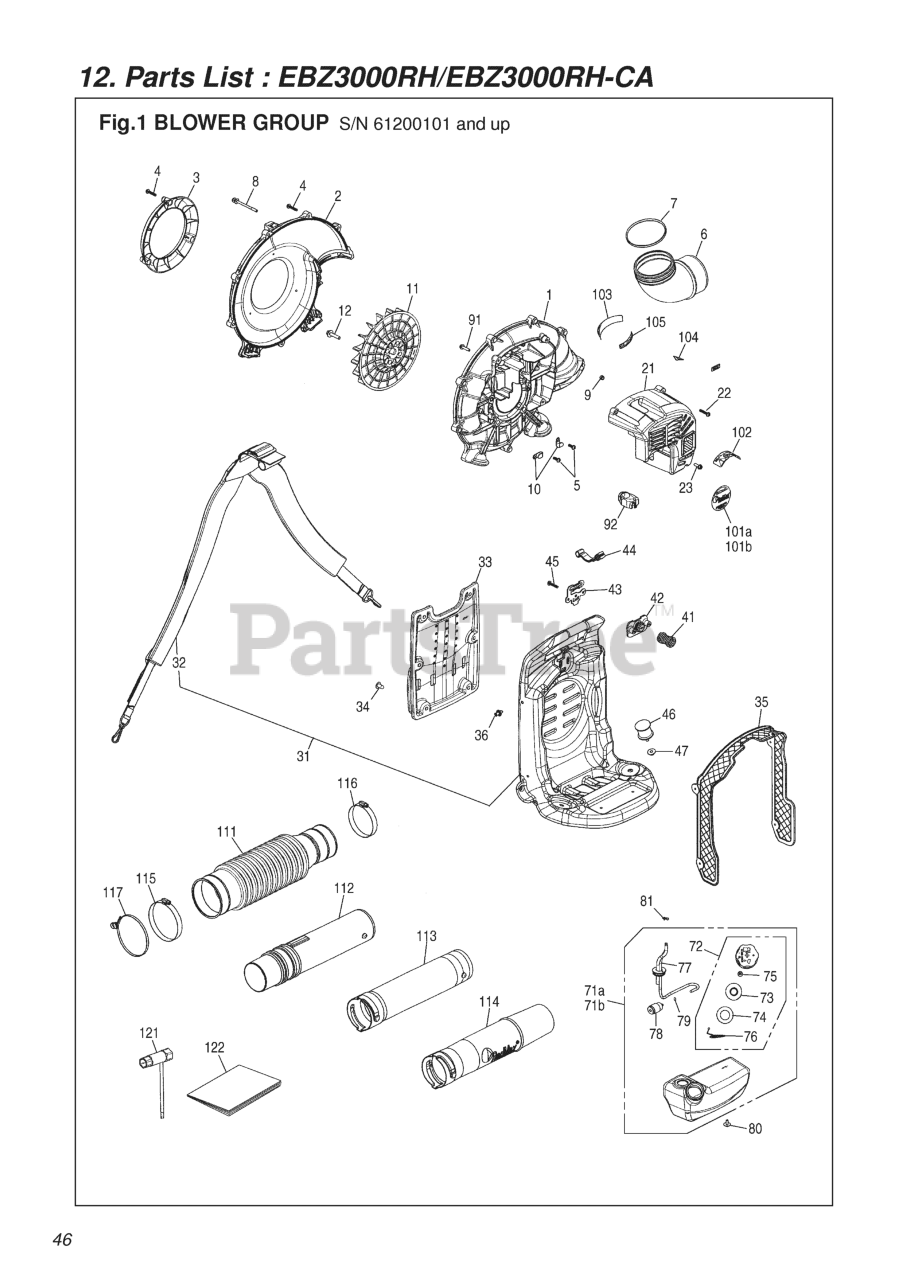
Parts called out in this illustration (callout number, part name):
1	VOLUTE CASE
2	VOLUTE COVER
3	FUNNEL
4	SCREW
6	ELBOW
8	SCREW TORX
9	NUT (B)
10	CLAMP (RPLS 1140-72231)
12	BOLT
21	COVER, ENGINE
22	SCREW
23	BOLT, TORX
31	FRAME ASSY
32	BAND ASSY
33	PAD
34	CLIP (RPLS 3490-21320)
35	NET
36	CLIP (RPLS 3490-21320)
42	HOLDER, SPRING
45	SCREW
46	DAMPER, LOWER
47	NUT, M6
71B	TANK ASSY
72	CAP ASSY (RPLS -85201)
73	HOLDER (REPLACES -85230)
74	PACKING
75	FILTER
76	STOPPER
77	PIPE COMP
78	FILTER ASSY
79	CLIP (REPLACES 2841-31280)
80	SCREW TORX
81	CLIP
91	BOLT
92	COVER
101B	LABEL, RECOIL
102	LABEL, CAUTION (RPLS -31910)
103	LABEL, NET
104	LABEL, HOTMARK
105	LABEL, SOUND
111	HOSE (RPLS 2750-51110)
112	SWIVEL-JOINT (REPLACES -51200)
113	PIPE, STRAIGHT
114	PIPE, END
115	CLAMP
116	CLAMP
117	BAND
